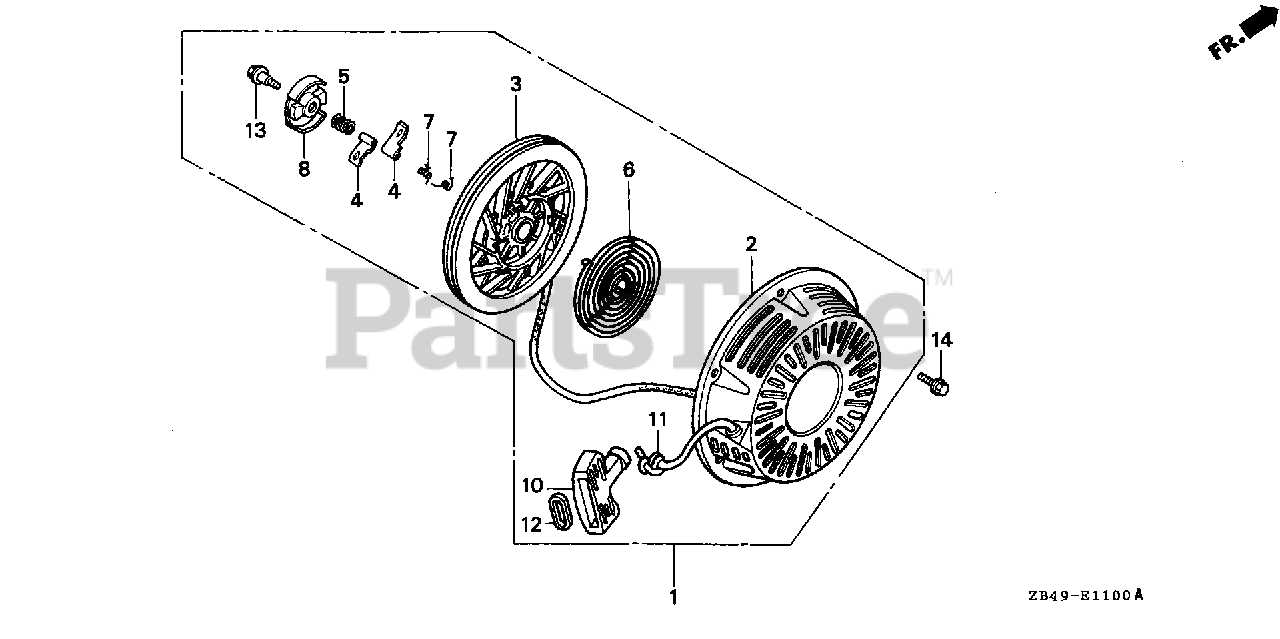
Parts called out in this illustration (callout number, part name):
1	STARTER ASSY., RECOIL *NH16M* (GUN METALLIC BLACK) (NOT AVAILABLE)
1	STARTER ASSY., RECOIL *NH1* (BLACK)
2	CASE, RECOIL STARTER *NH1* (BLACK)
2	CASE, RECOIL STARTER *NH16M* (GUN METALLIC BLACK)
3	PULLEY, RECOIL STARTER
4	RATCHET, STARTER
5	SPRING, FRICTION
6	SPRING, STARTER RETURN
7	SPRING, RATCHET
8	RETAINER, SPRING
10	GRIP, STARTER
11	ROPE, RECOIL STARTER
12	REINFORCEMENT, GRIP
13	SCREW, CENTER
14	BOLT, FLANGE (6X8)
